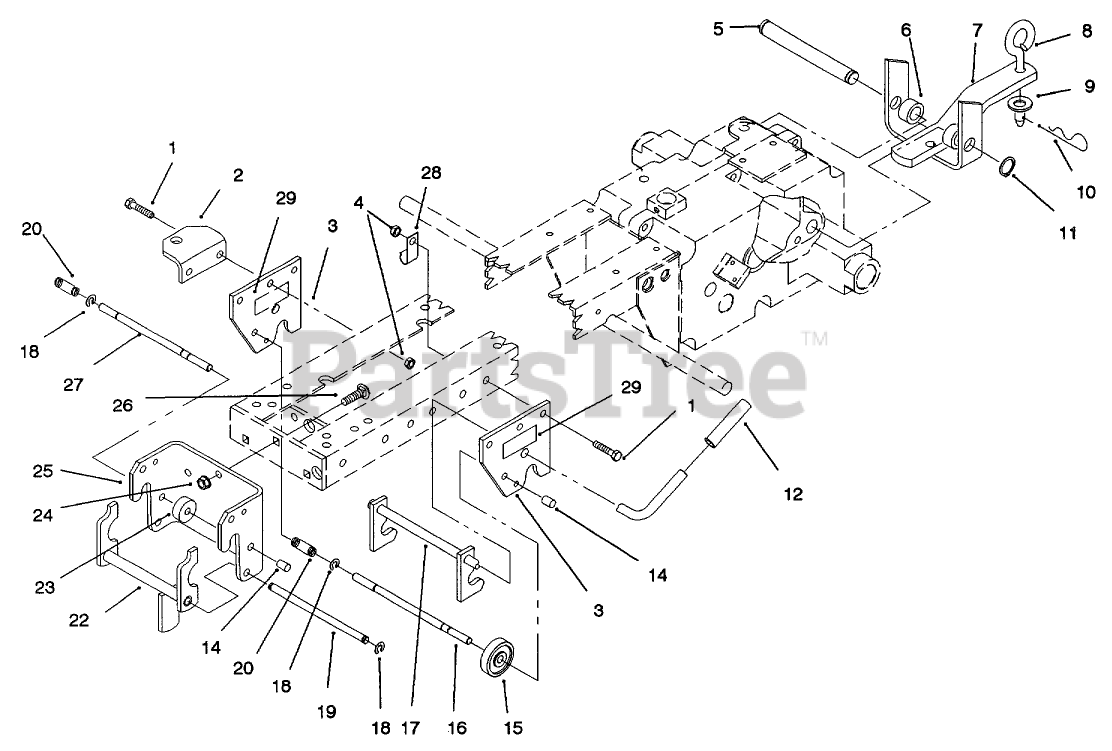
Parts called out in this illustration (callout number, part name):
1	SCREW-HH
3	PLATE-HITCH
4	NUT-HEX
5	PIN-STATIONARY HITCH
6	SPACER
8	PIN-TOOL
9	WASHER-FLAT
10	PIN-HAIR
11	E-RING
12	GRIP
14	CAP-ROD, PLUNGER
16	ROD-LOCK
17	MID HITCH ASM
18	RING-RETAINING
19	ROD-LATCH PIVOT
20	SPRING
22	LATCH
24	NUT-LOCK, NI
25	HITCH-FRONT
26	BOLT-CARR
27	ROD-LOCK
28	CLIP
29	DECAL-ATTACH A-MATIC
